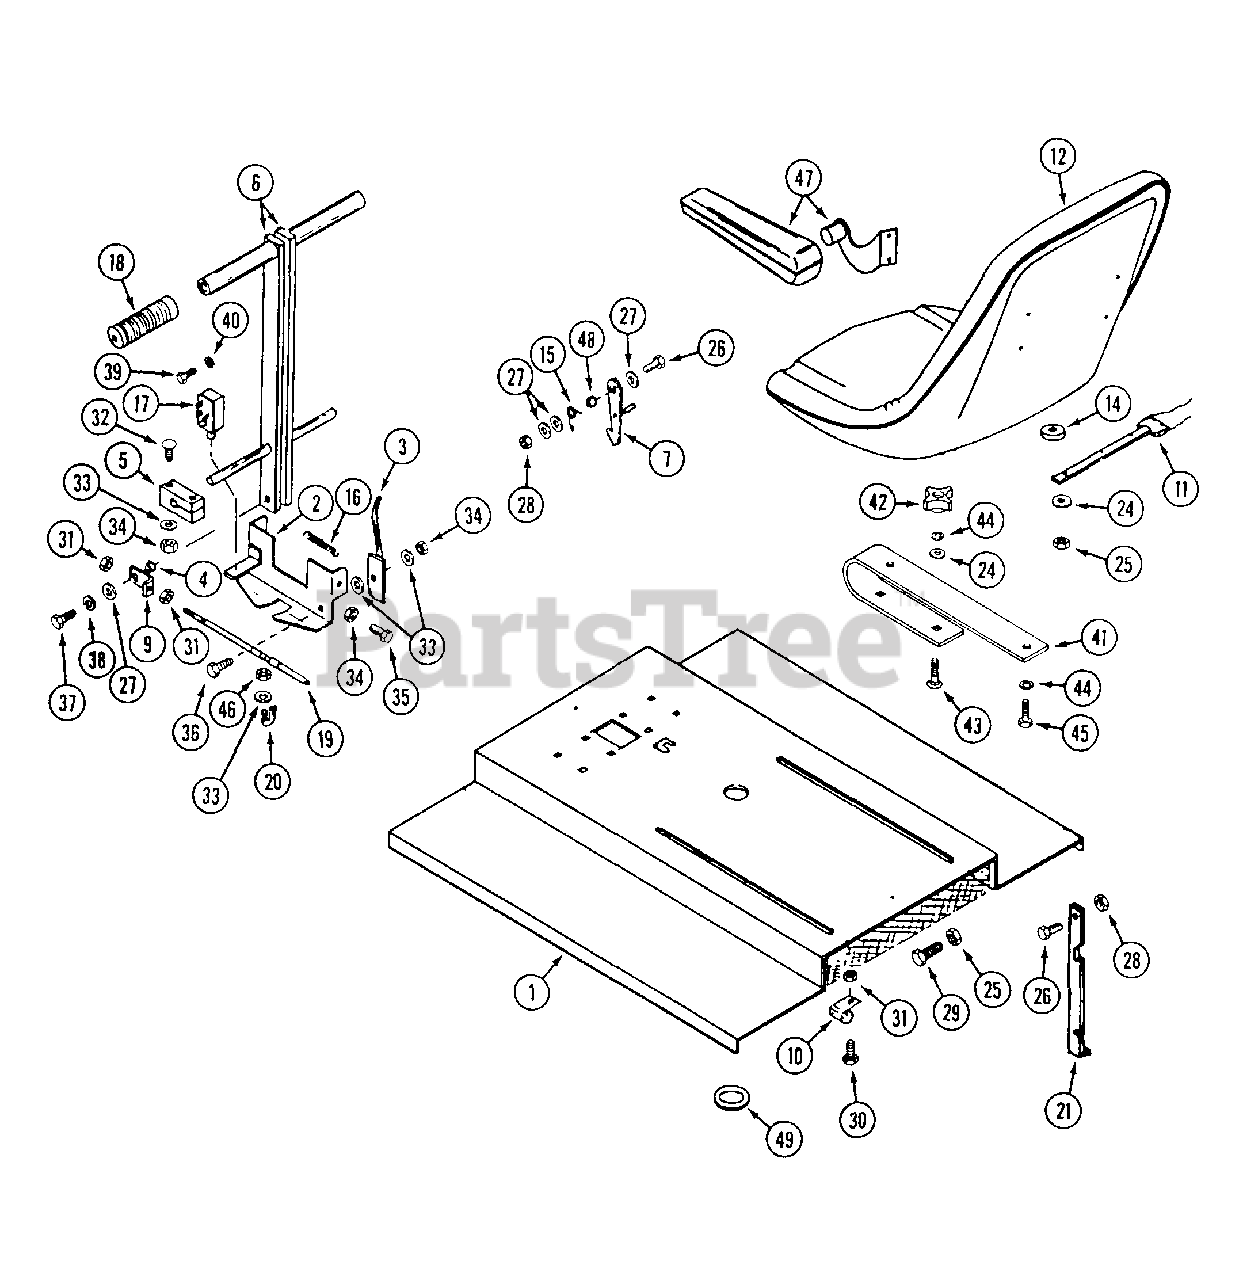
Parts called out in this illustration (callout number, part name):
2	BRACKET - lever lock
3	LATCH - lever lock
5	BEARING - block
6	LEVER - steering
7	LATCH - seat lid
9	BRACKET - steering cable end
10	RETAINER - harness, seat lid
15	SPRING - latch, seat lid
16	SPRING - bracket, lever lock
17	SWITCH - safety
18	GRIP - handle
19	CABLE - steering
20	CLAMP - steering cable
21	PROP - seat lid
24	WASHER - 5/16"
25	NUT - 5/16"
26	BOLT - 1/4" - 20 x 1"
27	WASHER - 1 /4"
28	NUT - 1/4" - 20 lock
29	BOLT - 5/16" - 18 x 1"
30	SCREW - #10 - 32 x 1/2"
31	NUT - #10 - 32
32	BOLT - 1/4" - 20 x 1-1/2" carriage
33	WASHER - 1/4"
34	NUT - 1/4" - 20 lock
35	BOLT - 1/4" - 20 x 3/4"
36	BOLT 1/4" - 20 x 2"
37	BOLT - 1/4" - 20 x 3/4"
38	LOCKWASHER - 1/4"
39	SCREW - #10 - 32 x 3/8"
40	LOCKWASHER - 3/16"
41	SPRING - seat
43	BOLT - carriage 5/16" - 18 x 1-1/4"
44	LOCKWASHER - 5/16"
45	BOLT - 5/16" - 18 x 1"
46	NUT - 1/4" - 20
47	KIT - arm rest
48	SPACER
49	GROMMET - 1/2" x 1"
